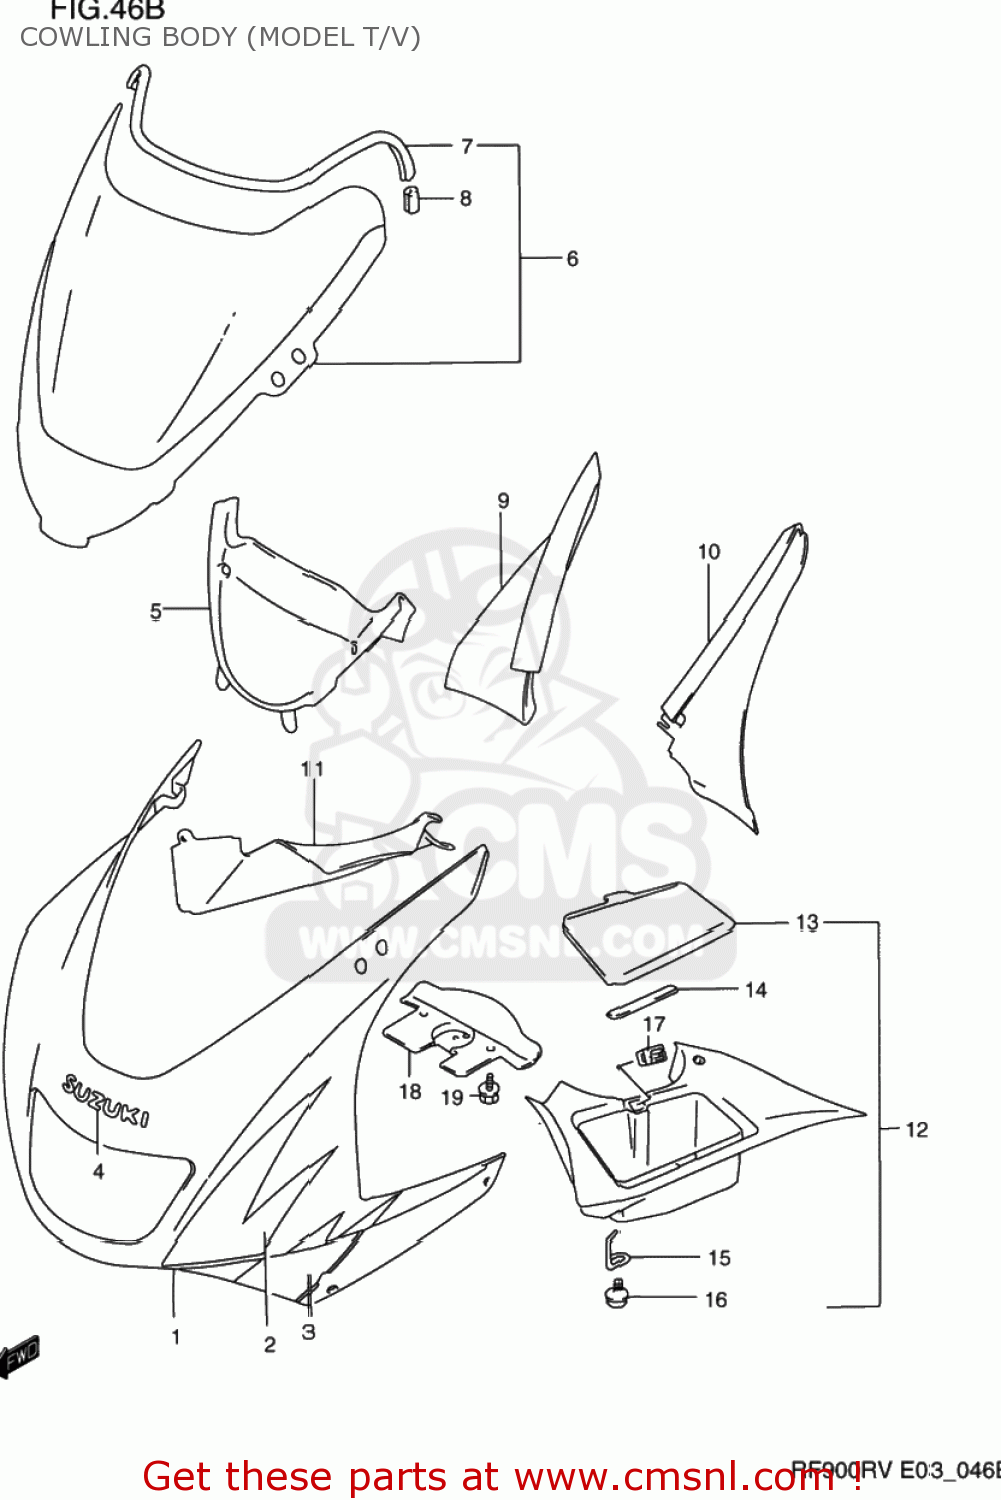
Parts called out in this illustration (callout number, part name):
1	COWLING ASSEMBLY,BODY
2	TAPE SET,BODY FR
3	TAPE SET,BODY SIDE
4	EMBLEM,COWLING UPR
5	PANEL,COWLING CTR
6	WINDSCREEN SET
7	MOLDING WINDSCREEN
8	CLIP,WINDSCREEN MOLDING
9	PANEL,UPR,R
10	PANEL,UPR,L
11	PANEL,SIDE,R
12	PANEL ASSY,SIDE,L
13	LID,PANEL BOX
14	CUSHION,LID
15	HINGE,PANEL LID
16	SCREW
17	LOCK,I/P CTR BOX
18	COVER,COWLING FR LWR
19	BOLT(6X12)
